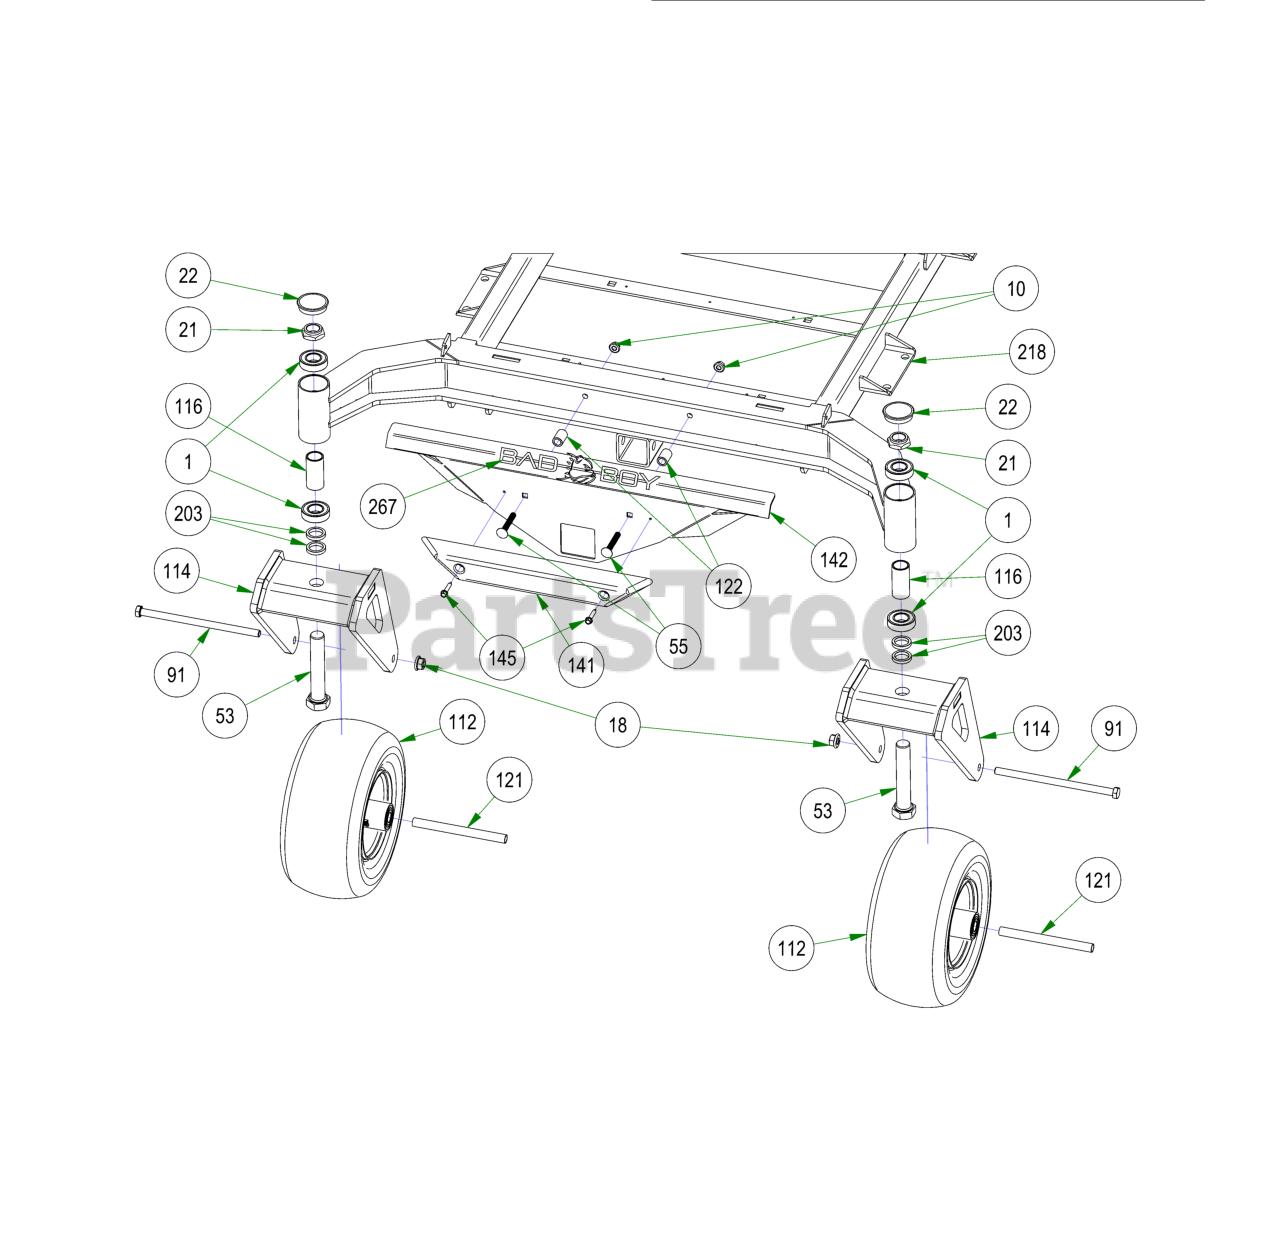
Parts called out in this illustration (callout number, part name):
1	1641 BEARING W/2 CONTACT RUBBER SEALS
10	3/8-16 NYLON INSERT FLANGE LOCKNUT (GR.F) ZINC
18	1/2-13 NYLON INSERT FLANGE LOCKNUT ZINC
21	1"-14 NYLON INSERT JAM LOCKNUT ZINC
22	2017 Bearing Cover
53	1"-14 X 5-1/2 HEX CAP SCREW (GR.8) ZINC YELLOW
55	3/8" x 2 1/2" Carriage Bolt
91	1/2-13 X 9 HEX CAP SCREW (GR.5) ZINC
112	13x6.50-6 Black No Flat Assembly
114	2019 Rebel Front Fork - Weldment - Black
116	2016 Front Bearing Spacer
121	Front Wheel Spanner
141	2017 XP Bumper
142	2019 Outlaw Rigid Front Bumper Plate
145	1/4-14 X 1-1/2 HEX WASHER UNSLOT TEK/3 ZINC
203	1.02 ID X 1.38 OD X .250 THK SPACER ZINC
218	2022 Rebel Frame
267	Flying Bulldog Front Bumper Decal
